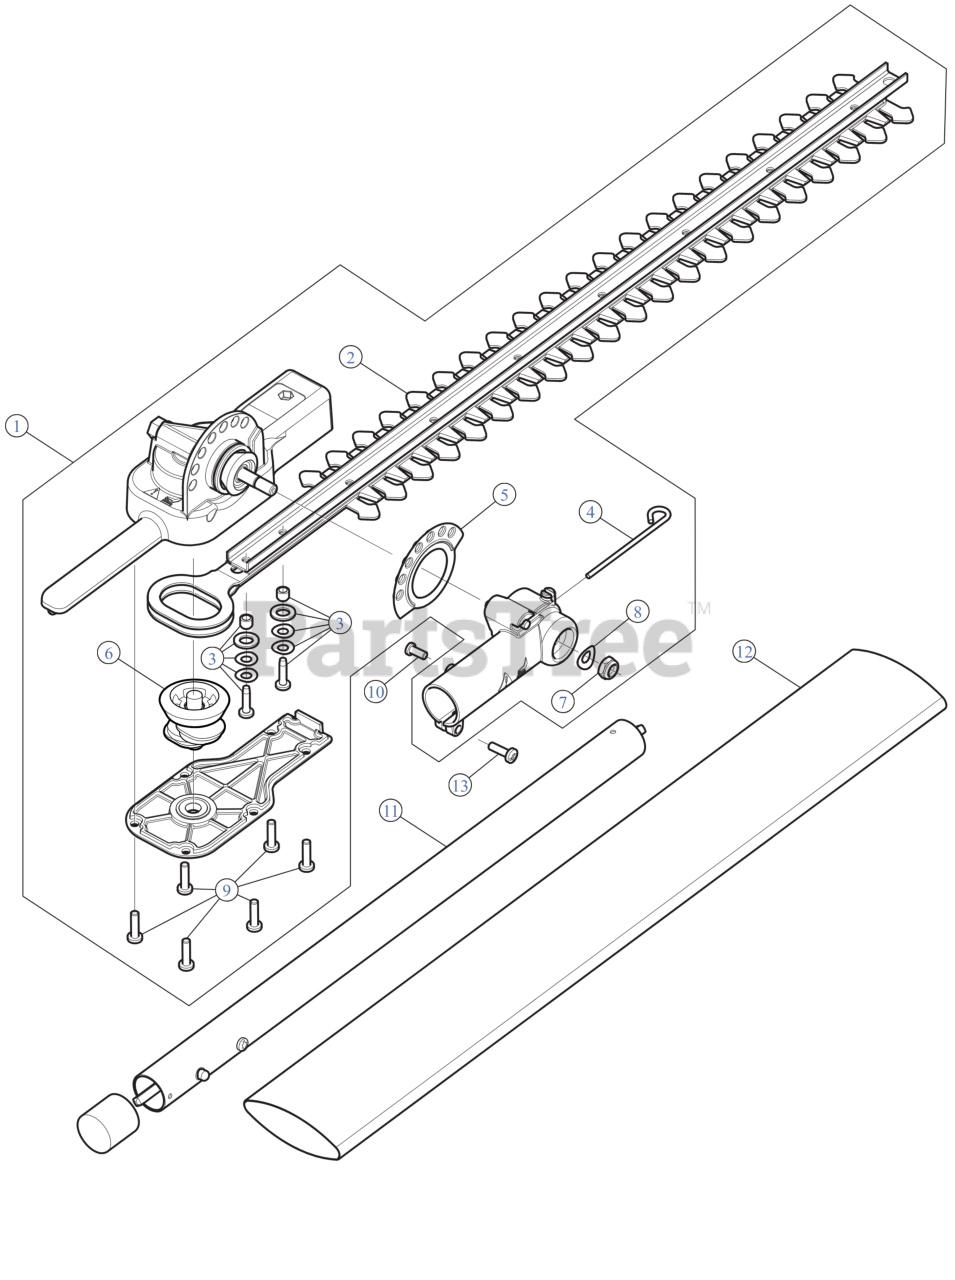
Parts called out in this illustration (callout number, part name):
1	GEARBOX ASSEMBLY
2	BLADE ASSEMBLY
3	BLADE HARDWARE
4	LOCKING LEVER PIN
5	SPACER DETENT SHM
7	NUT 5/16-24
8	SHAKE PROOF WASHER
9	SCREW - 10-24X.625 PAN HEAD
10	SCREW 8-32X.437
11	BOOM ASSEMBLY
12	BLADE COVER
13	SCR, M5 x 15.8MM
